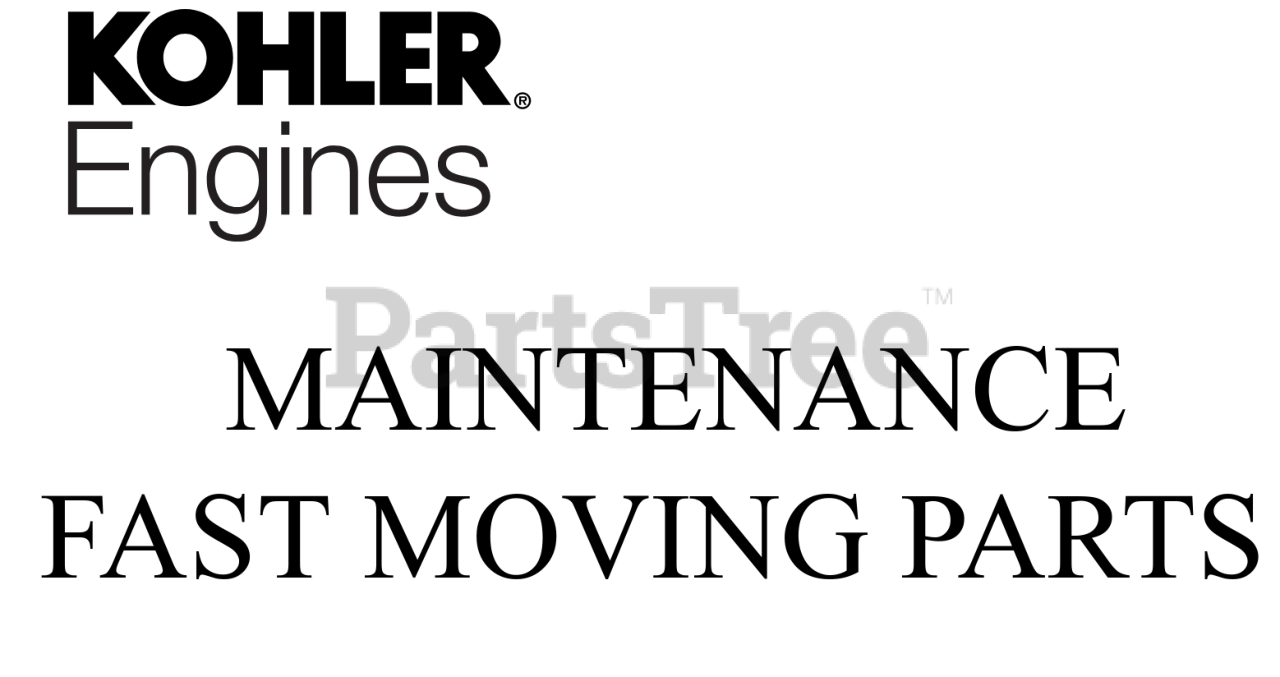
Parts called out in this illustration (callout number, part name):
NI	FILTER, BREATHER MEDIA (LOWER HALF)
NI	FILTER, BREATHER MEDIA (UPPER HALF)
NI	MAINTENANCE KIT, 824CC
NI	FILTER, FUEL
NI	ELEMENT, AIR FILTER - PRIMARY
NI	PLUG, SPARK
NI	OIL FILTER
